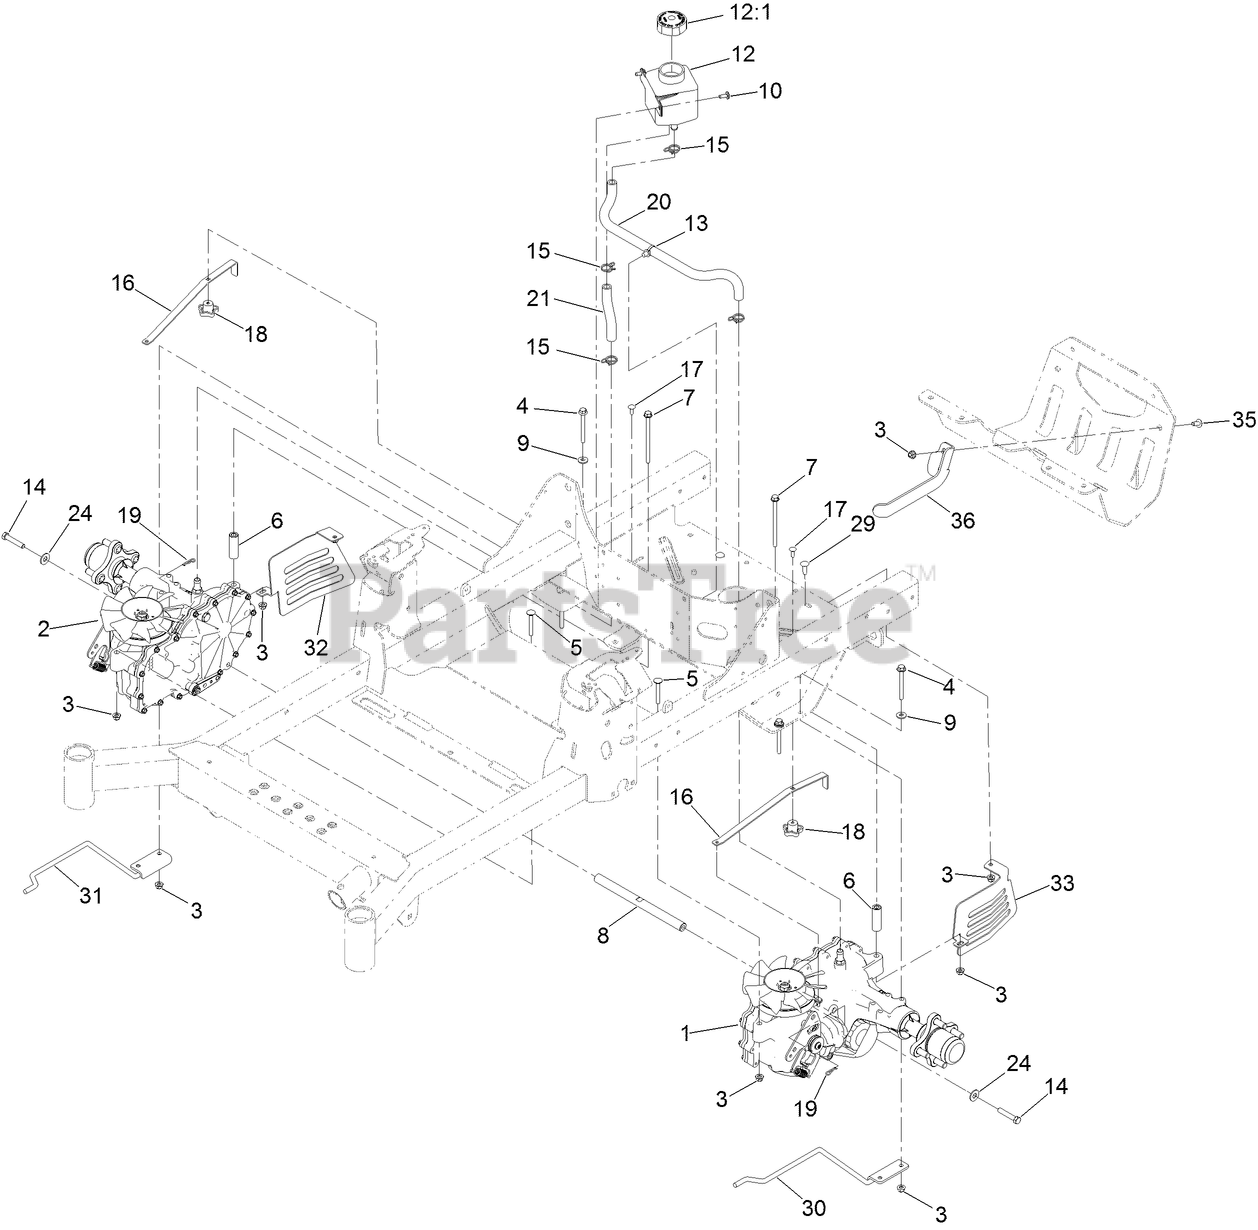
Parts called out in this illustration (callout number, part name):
1	LH TRANSAXLE ASM
2	RH TRANSAXLE ASM
3	NUT-HF, NI
4	SCREW-HHF
5	BOLT-CARR
6	SPACER-HYDRO
7	SCREW HHF
8	SHAFT-SPACER
9	WASHER-SPRING
10	SCREW-TORX
12	TANK-HYD
12:1	CAP-RESERVOIR, HYD
13	CLIP-TIE
14	SCREW-HH W/LOCTITE
15	Clamp-Hose
16	ARM-BYPASS, HYDRO
17	BOLT-CARR
18	KNOB-HANDLE
19	PIN-COTTER
20	HOSE-HYDRAULIC
21	HOSE-HYDRAULIC
24	WASHER-FLAT
29	SCREW-CARR
30	SUPPORT-UPPER, LH
31	SUPPORT-UPPER, RH
32	GUARD-CLUTCH, RH
33	GUARD-CLUTCH, LH
35	SCREW-TORX
36	BRACKET-GUARD, MUFFLER
